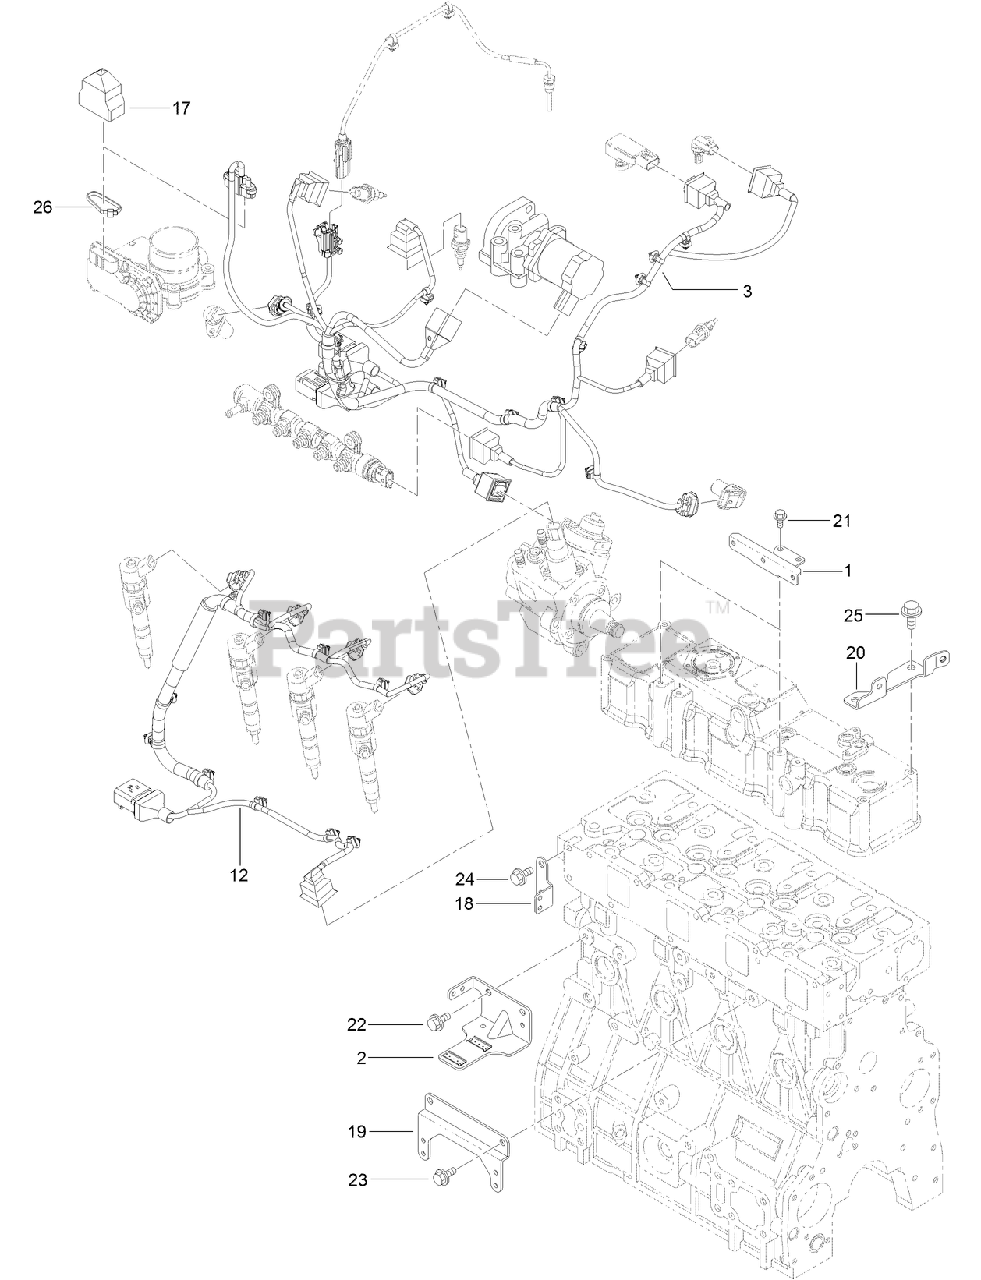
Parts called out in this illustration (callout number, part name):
1	BRACKET-HARNESS
2	BRACKET-CONNECTOR
3	HARNESS-B, E C O
12	HARNESS-C, E C O ENGINE
17	BOOT-CAP
18	BRACKET-HARNESS
19	BRACKET-HARNESS
20	BRACKET-HARNESS
